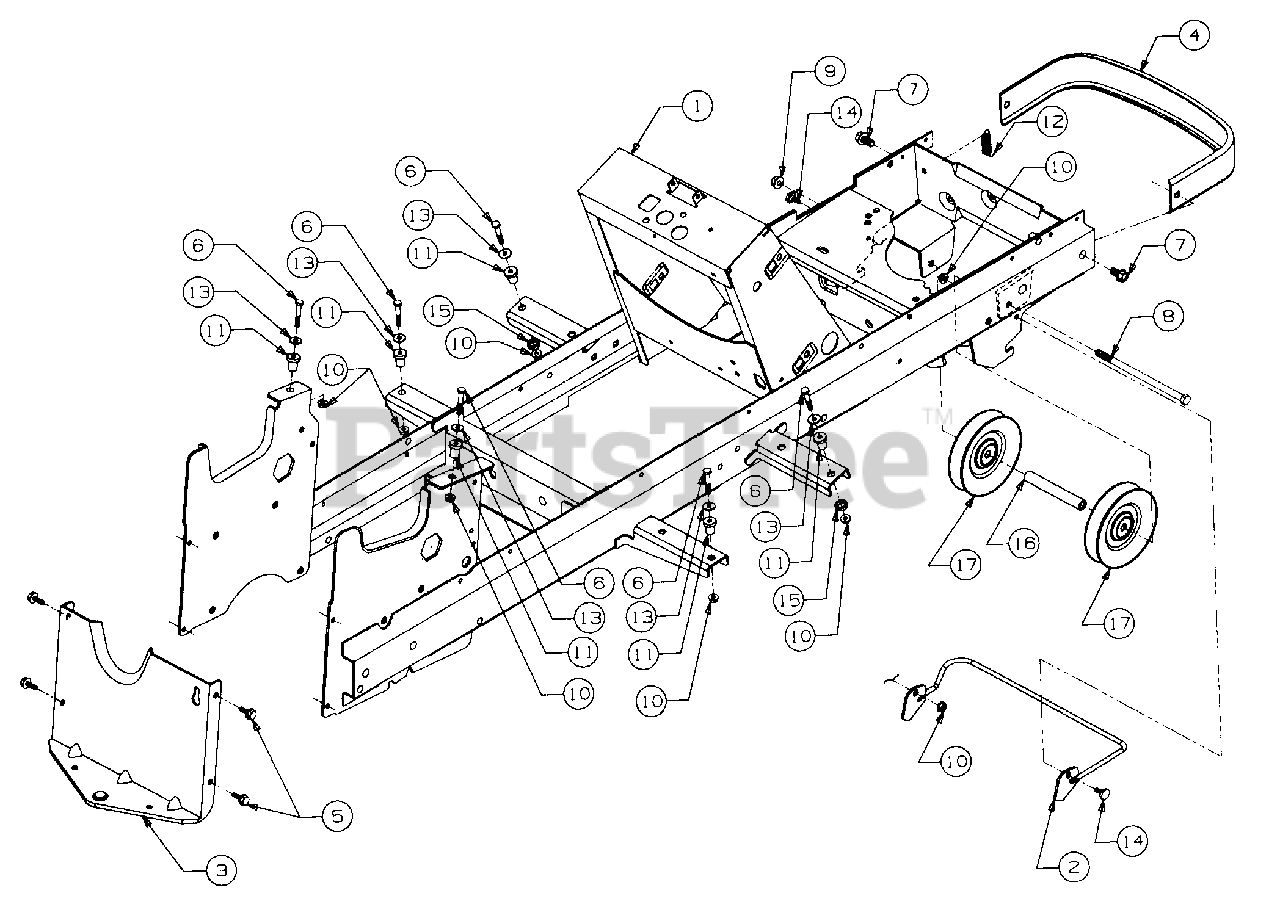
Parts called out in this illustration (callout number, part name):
6	Screw, Hex Cap, 1/4-20 x 1.5 Lg
7	Screw, Hex Wash Tapp 3/8-16 x .75 Lg
8	Screw, Hex Cap, 3/8-16 x 7.0 Lg
9	Nut, Hex Flanged Lock, 3/8-16
10	Nut, Hex Flange Lock, 1/4-20
11	Insolater, .50 OD x .88 Lg
12	Spring, Latch
13	Washer, Flat, .255 x .720 x .060 Thk
14	Bolt, Shoulder
15	Spacer, .511 ID x .70 OD x .38 Lg
16	Spacer, Idler, .407 ID x .62 OD x 4.38 Lg
17	Pulley, Idler
